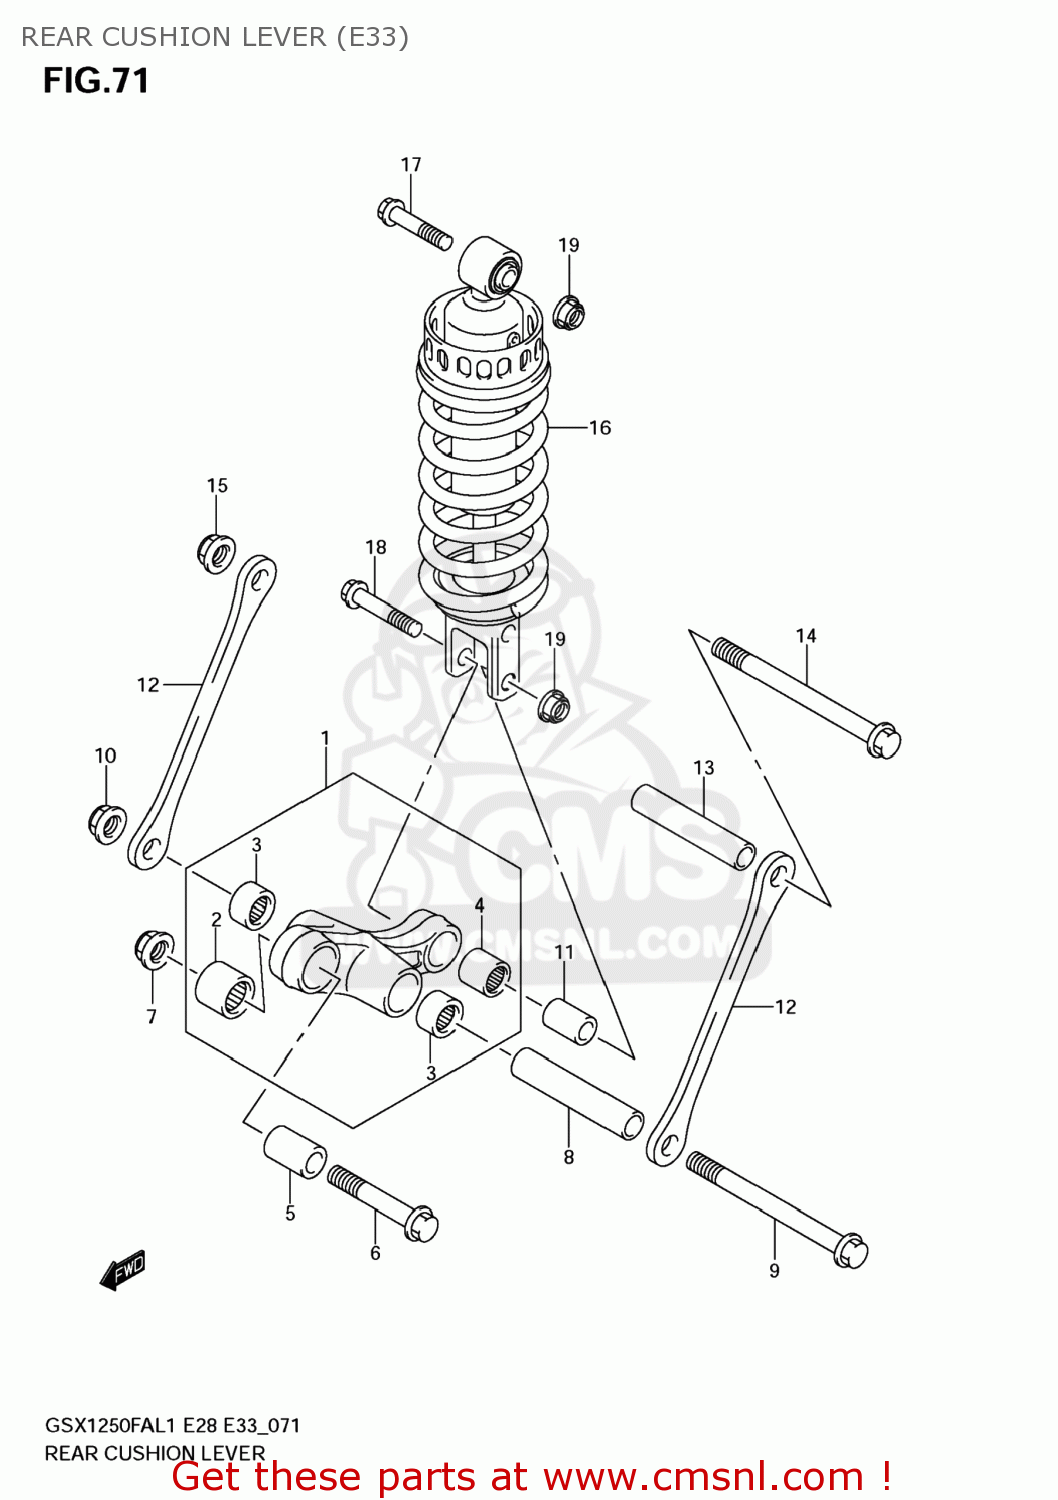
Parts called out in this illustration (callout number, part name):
1	LEVER SET,RR CUSHION
2	BEARING(20X27X26)
3	BEARING(17X24X25)
4	BEARING(17X24X26)
5	SPACER,RR CUSHION LEVER FR
6	BOLT,CUSHION LEVER FR
7	NUT
8	SPACER,RR CUSHION LEVER CTR
9	BOLT,RR CUSHION LEVER CTR
10	NUT
11	SPACER,RR CUSHION LEVER
12	ROD,RR CUSHION
13	SPACER,RR CUSHION LEVER CTR
14	BOLT,RR CUSHION LEVER CTR
15	NUT
16	ABSORBER ASSY,RR SHOCK
17	BOLT(10X52)
18	BOLT(10X55)
19	NUT
